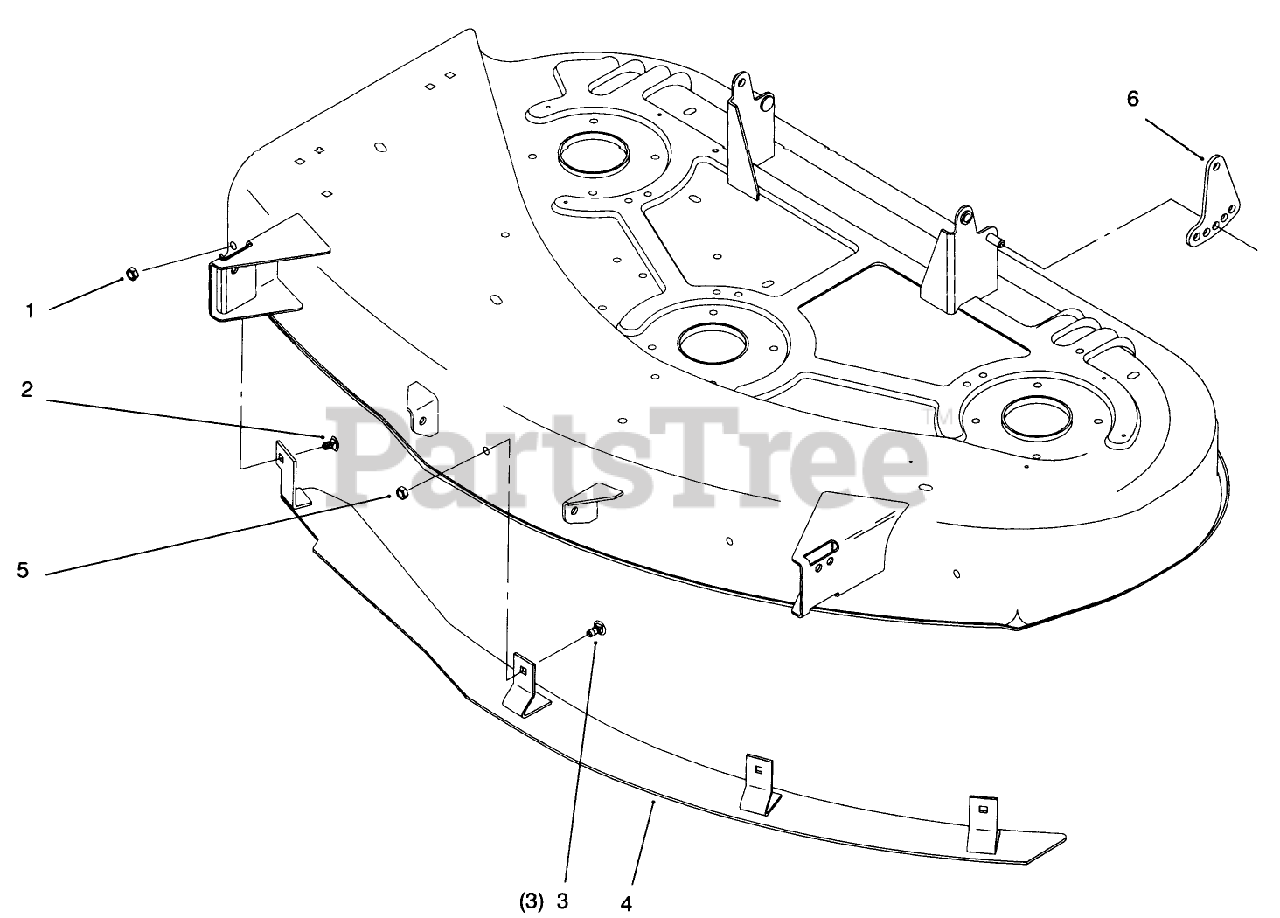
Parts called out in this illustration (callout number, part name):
1	NUT-LOCK, NI
2	BOLT-CARR
3	SCREW-CARR
5	NUT-LOCK, NI
